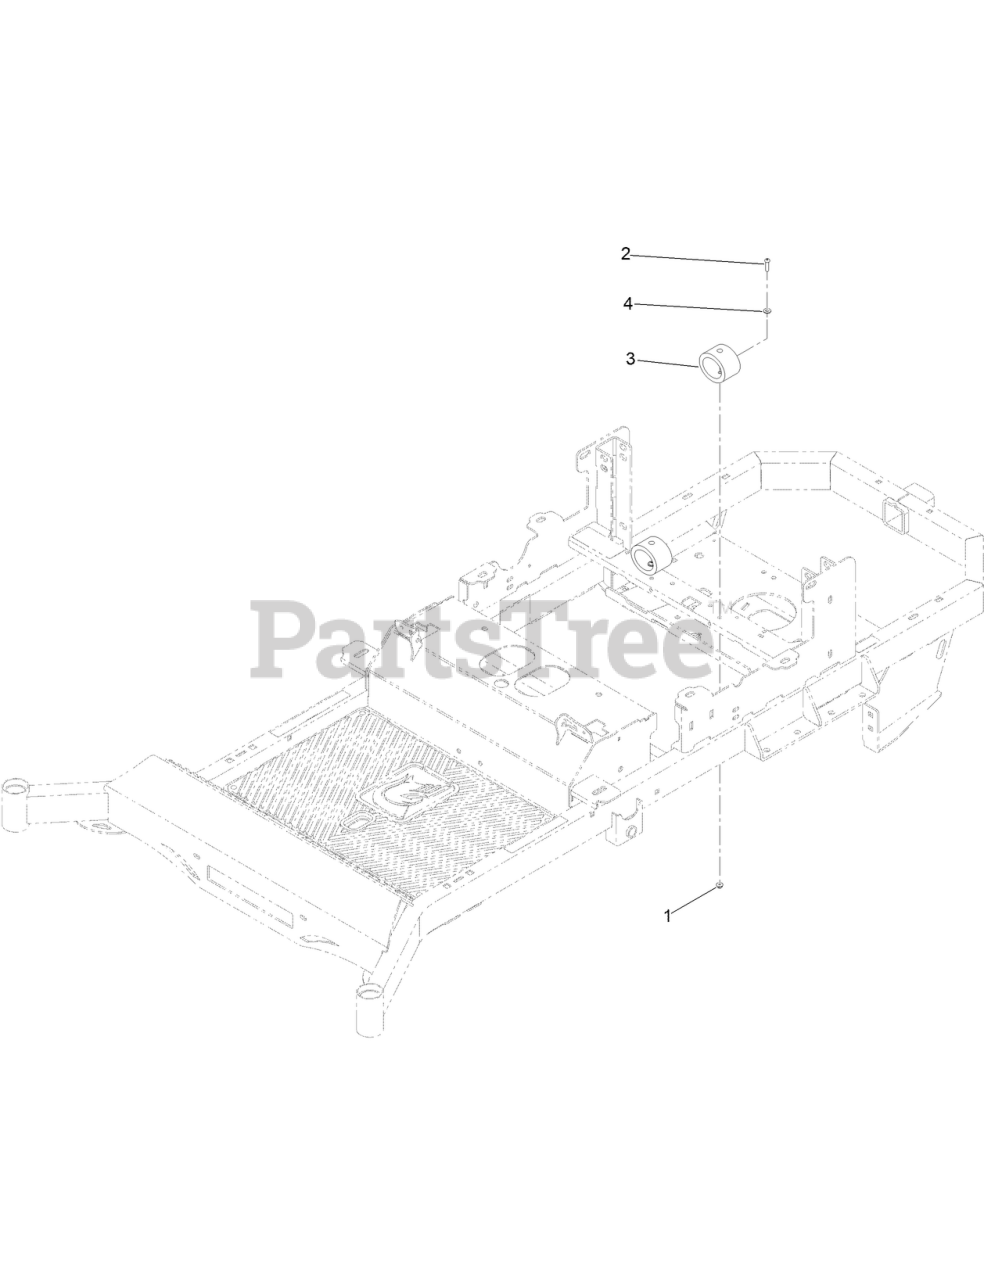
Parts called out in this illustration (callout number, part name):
1	NUT-HF
2	1/4-20 X 1 BUTTON SOCKET C/S 18-8 SS
3	SEAT RR SUSP ELASTOMER
4	WASHER-FLAT
